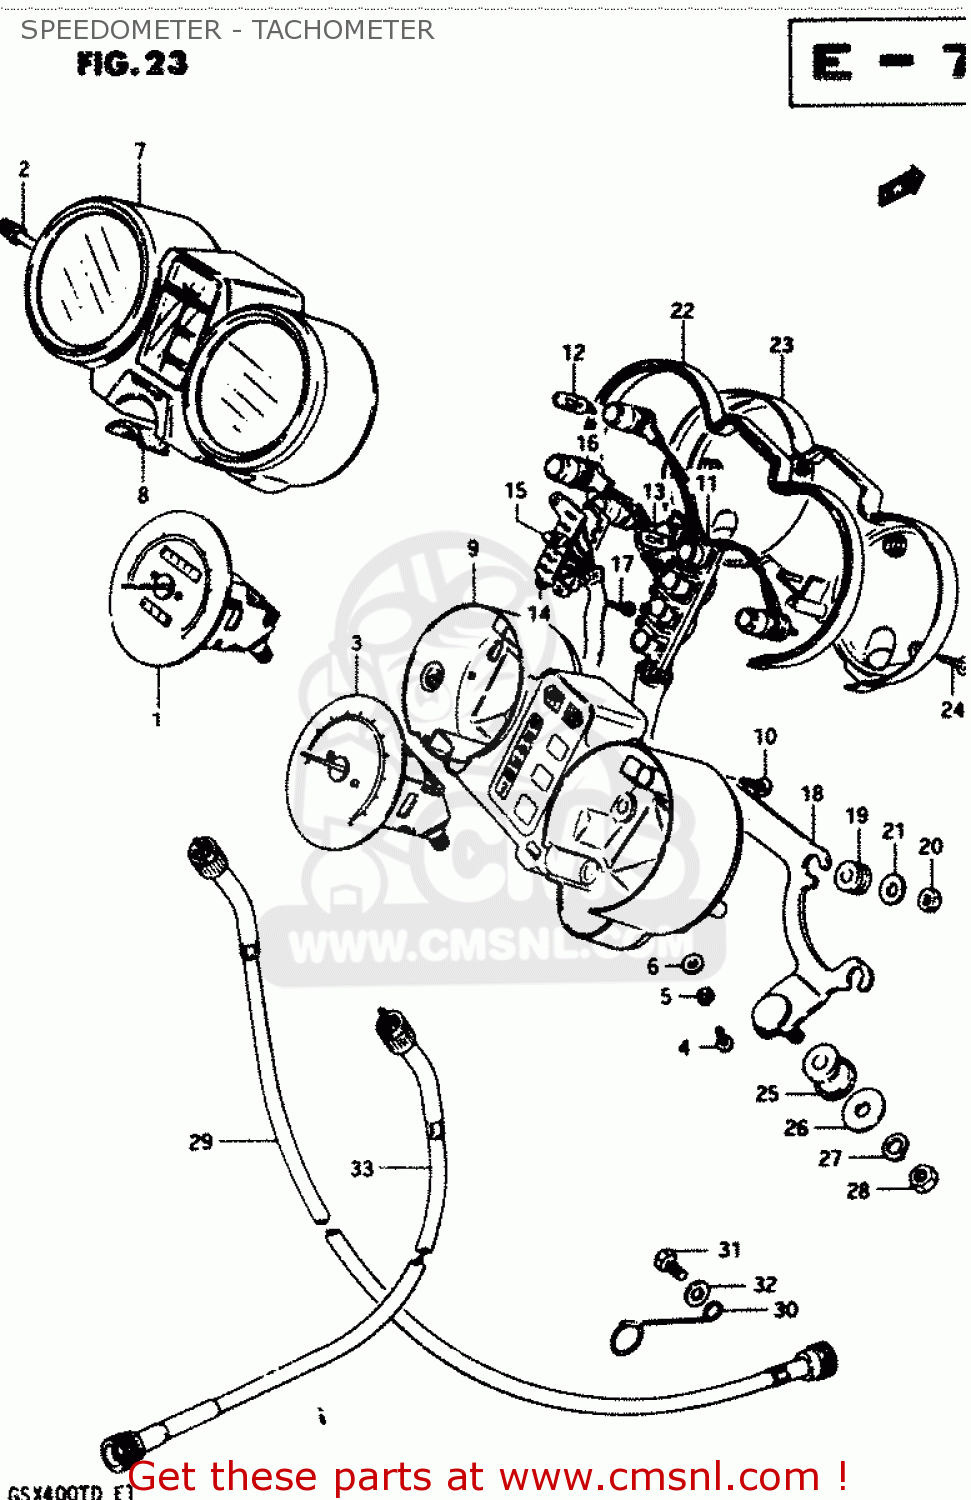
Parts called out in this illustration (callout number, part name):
1	SPEEDOMETER (KILO)
2	KNOB
3	METER,TACHOMETER
4	SCREW 4X10
5	WASHER
6	LOCK WASHER
7	HOOD,METER
8	SEAL,IGNITION SWITCH
9	CASE,METER,INNER
10	SCREW
11	SOCKET
12	BULB(12V3.4W,T10)
13	BULB(12V1.7W,T10,WB121)
14	SOCKET,GEAR INDICATOR
15	BULB(14V1.12W,BQ041-32503B)
16	COVER,INDICATOR,LOWER
17	SCREW
18	BRACKET,COMBINATION METER
19	CUSHION,METER
20	NUT
21	WASHER (5.5X16X1.2)
22	COVER,METER,UNDER
23	COVER,LWR
24	SCREW
25	CUSHION,METER BRACKET
26	WASHER (8.5X20X1.6)
27	LOCK WASHER
28	NUT
29	CABLE ASSY,SPEEDOMETER
30	CLAMP,SPEEDOMETER CABLE
31	BOLT, UPPER
32	WASHER
33	CABLE ASSEMBLY,TACHOMETER
